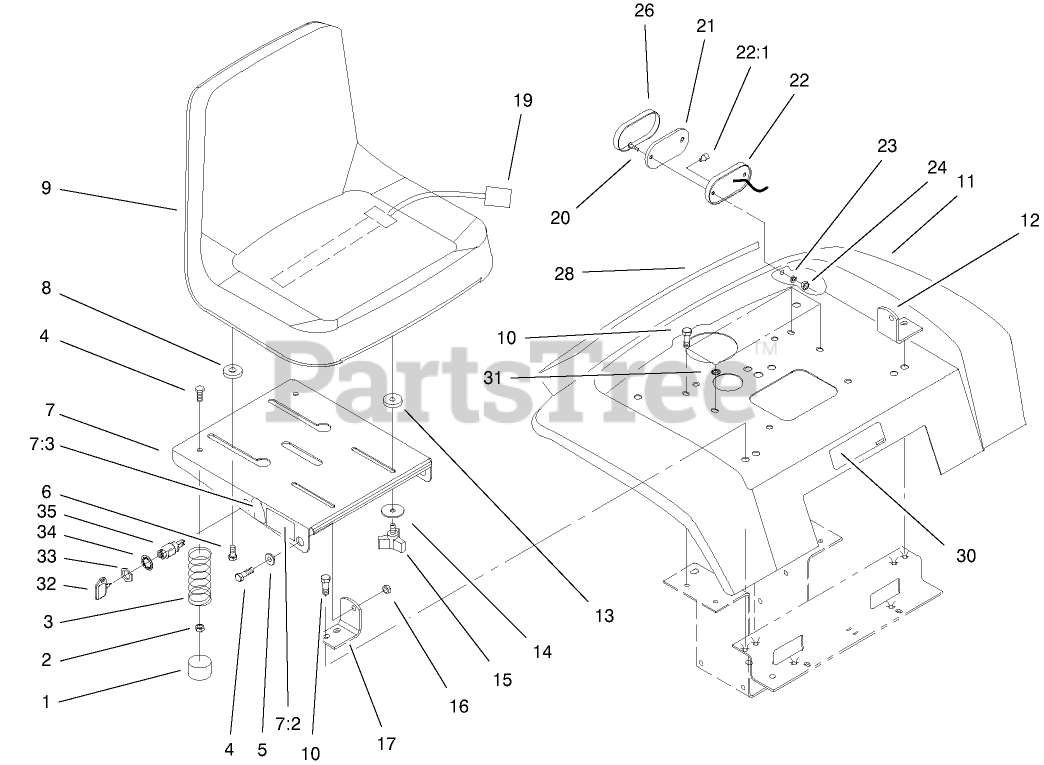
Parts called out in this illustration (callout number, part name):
1	CAP-PROTECTOR
2	NUT-LOCK, NI
3	SPRING-COMPRESSION
4	SCREW-HH
5	BUSHING
6	BOLT-SHOULDER
7	SUPPORT-SEAT
7:2	DECAL-DANGER
7:3	DECAL-SWITCH, NMIR
8	SPACER-NYLON
10	SCREW-HWHTF
12	BRACKET-PIVOT, LH
13	SPACER-NYLON
14	WASHER
16	NUT-LOCK, NI
17	BRACKET-PIVOT, RH
19	SWITCH-SEAT
20	SCREW-PPH
22:1	LIGHT BULB
23	WASHER-LOCK, INT
24	NUT-LOCK, NI
26	LENS-TAIL LIGHT
30	DECAL - USA
31	WASHER-LOCK
32	KEY-IGNITION
33	NUT-HH
34	WASHER-LOCK
35	STARTER SWITCH ASM
